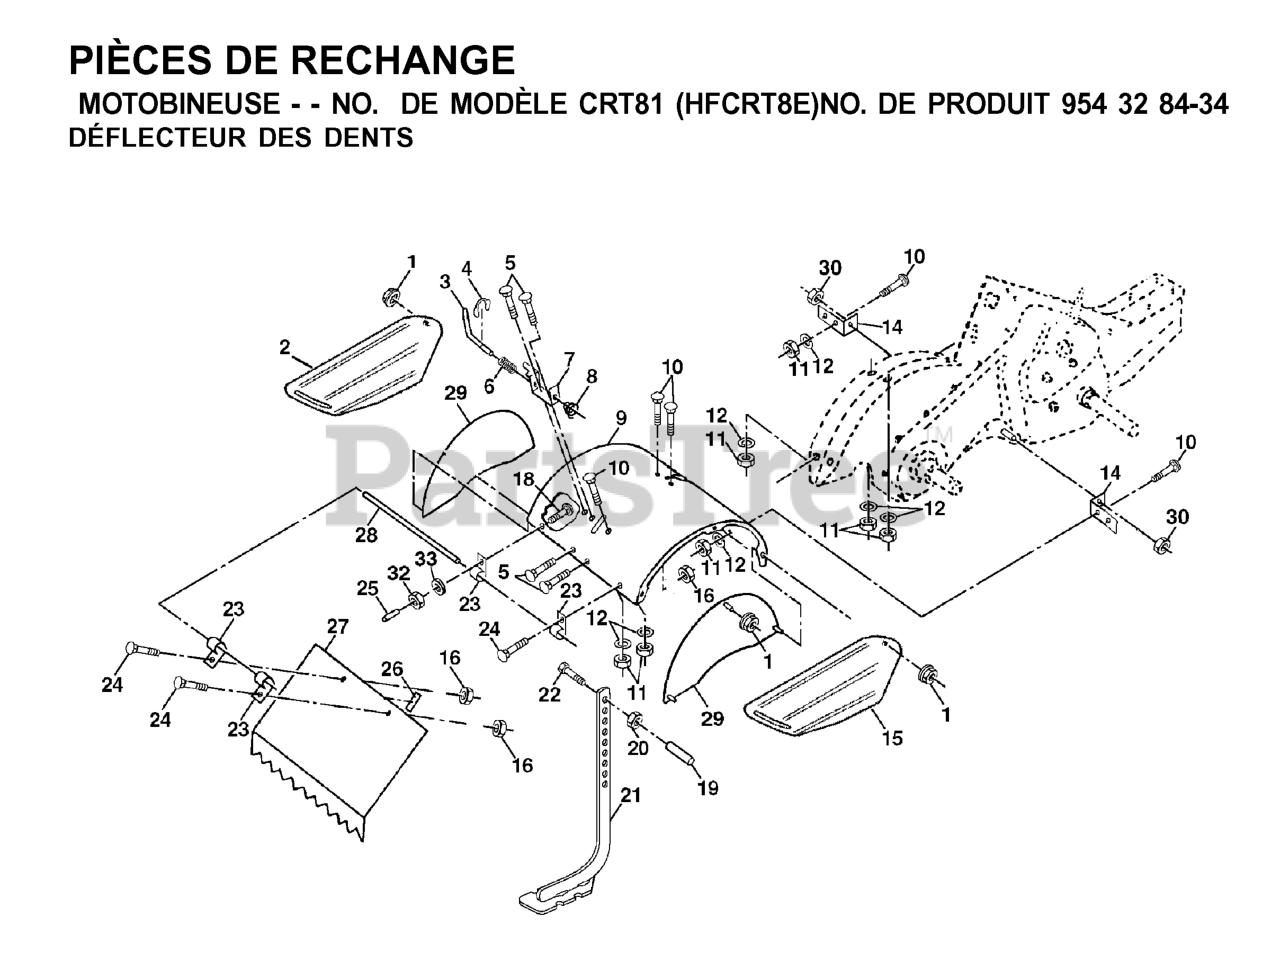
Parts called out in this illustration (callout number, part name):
1	NUT LOCK HEX FLANGE 5/16-18
2	TINE SHIELD
3	STAKE PIN TI
4	KLIP RING TI
5	BOLT
7	BRACKET.LATCH.STAKE.3.20.BLACK
8	SPRING CRT
9	SHIELD TINE
10	RP BOLT 5/16-18 X3/4 ZN/YEL GR
11	NUT
12	WASHER.LOCK.HVY.HLCL.SPR.5/16
14	BRACKET.TINE.SHIELD.TILLER
15	SHIELD
16	NUT T
20	NUT.HEX.3/8-16UNC
21	STAKE.ASM.DEPTH
22	BOLT.375-16
24	BOLT
25	VINYL CAP TI
26	PAD IDLER TI
27	SHIELD.LEVELING.21".ORANGE
28	PIN, HINGE
29	SHIELD, SIDE
30	LOCKNUT-FLANGE 5/16-18
32	NUT
33	LOCKWASHER
